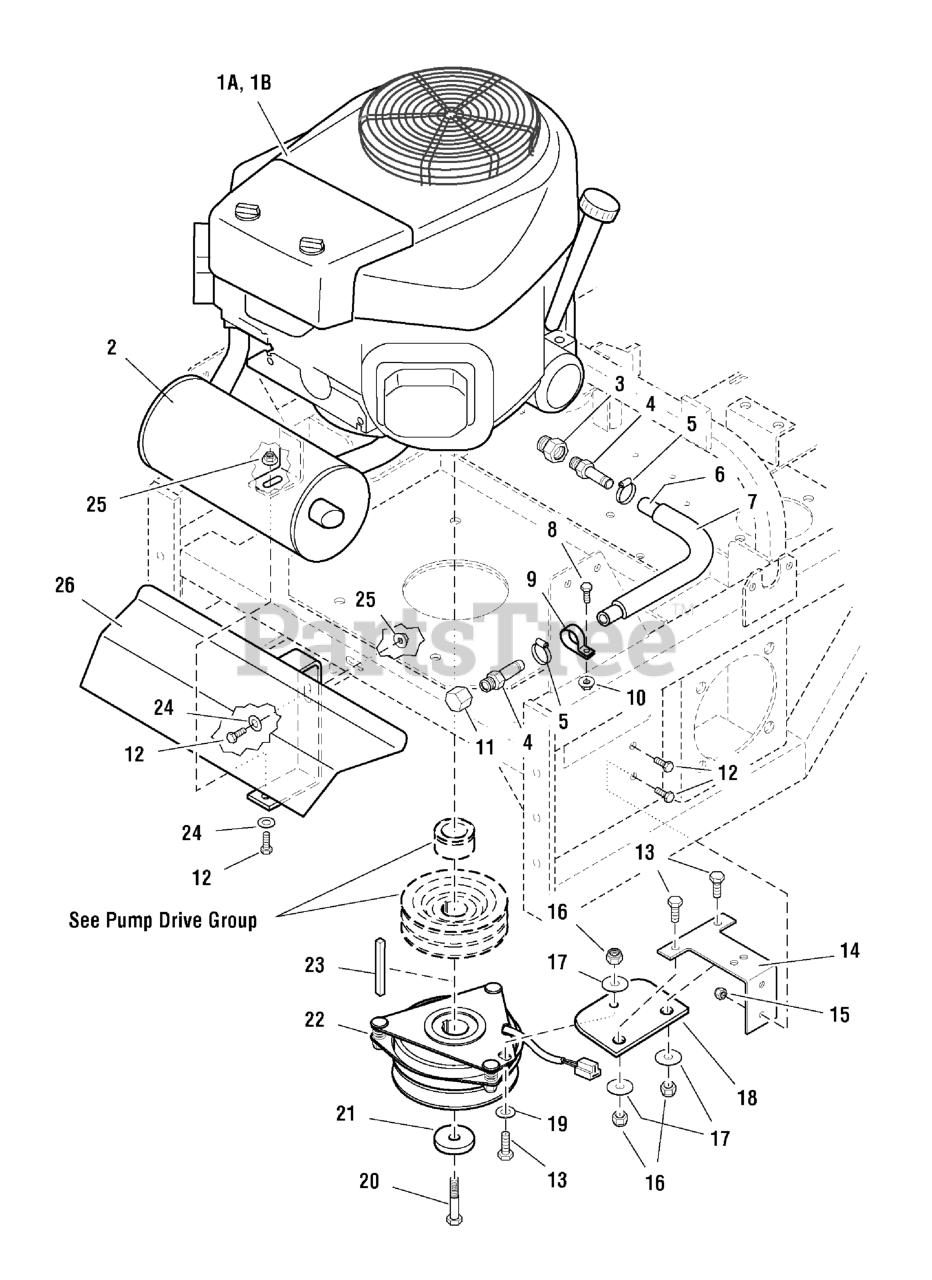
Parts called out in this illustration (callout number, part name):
1B	FUEL FILTER
1B	OIL FILTER (49065-2078)
2	MUFFLER
3	ADAPTER, Oil Drain
4	FITTING, 3/8NPT-1/2" Hose, Straight
5	CLAMP, #6 Hose
6	HOSE, 9"
7	WIRE LOOM, 7"
8	BOLT, 1/4-20 x 3/4
9	CLAMP, Vinyl
10	NUT, 1/4-20 HEX SERR. FLANGE
11	CAP, 3/8 NPT
12	BOLT, 5/16-18 X 3/4 GD5
13	BOLT, 3/8-16 X 1" GD5 CZ
14	CLUTCH ANCHOR
15	NUT, 5/16-18 Hex Nylon Lock
16	NUT, 3/8-16 HEX NYLON LOCK
17	WASHER, 3/8" Fender
18	CLUTCH ANCHOR PAD
19	WASHER, 3/8 SAE
20	CRANKSHAFT BOLT, 7/16 x 2
21	SPACER, .45 x 1.88 x .38
22	ELECTRIC CLUTCH
23	KEY, 1/4 SQ. X 3-1/2
24	WASHER, 5/16" SAE
25	NUT, 5/16-18 HEX SERRATED FLANGE (SMALL)
26	MUFFLER SUPPORT
